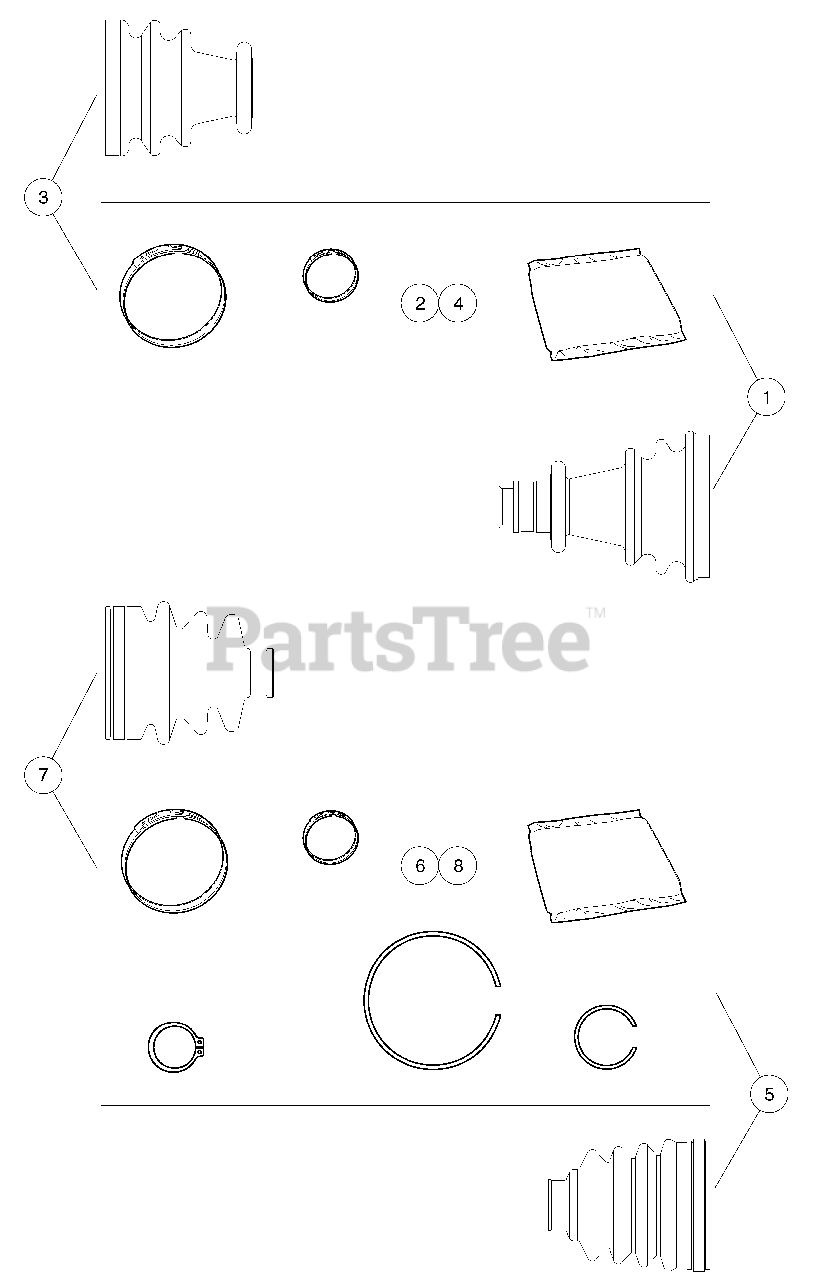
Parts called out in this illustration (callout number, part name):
1	Boxed Outboard Boot Kit
2	Half Shaft Boot Instl. Instr.
3	Boxed Inboard Boot Kit
4	Half Shaft Boot Instl. Instr.
5	Kit, Outer Boot, Gen 2
6	Instructions, Boot Replacement
7	Kit, Inner Boot, Gen 2
8	Instructions, Boot Replacement
